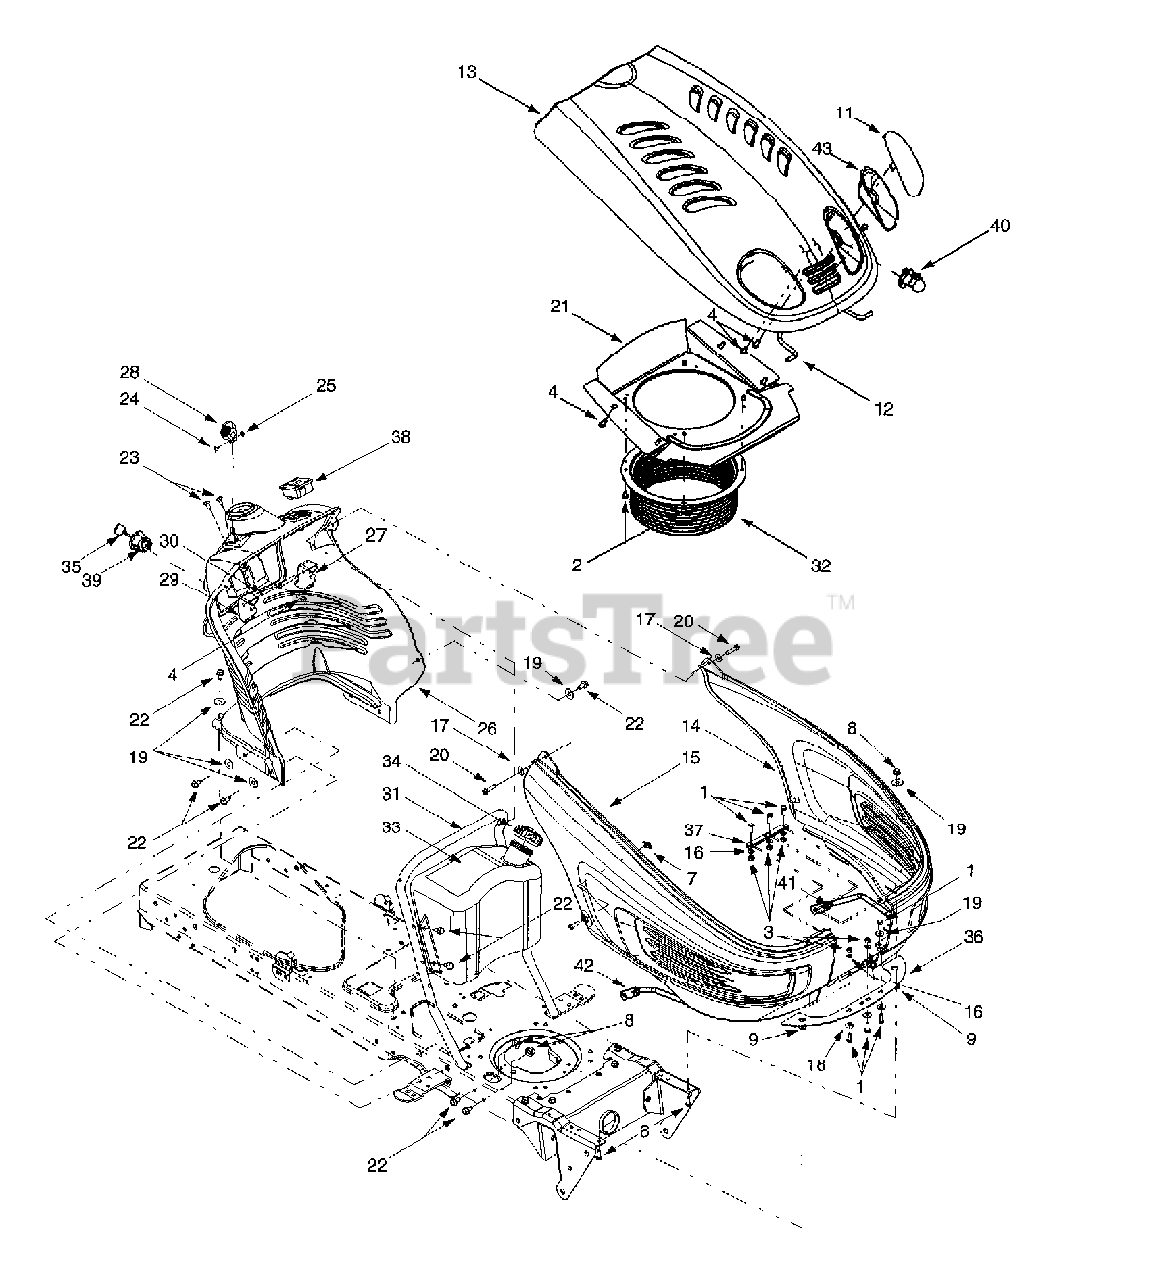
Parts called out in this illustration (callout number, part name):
1	Hex Cap Screw, 1/4-20 x .75
2	Self-tapping Screw, 1/4-20 x.5
3	Hex Nut, 1/4-20
4	Self-tapping Screw, 1/4-15 x .75
6	Hex Cap Screw, 5/16-18 x 1.25
7	U-type Speed Nut, 1/4-20
8	Flange Lock Nut, 5/16-18
9	Speed Nut
11	RH Head Light Lens
12	Hood Support Rod
13	Hood
14	LH Side Panel
15	RH Side Panel
16	Lock Washer, 1/4
17	Flat Washer, .283 x .75 x .030
18	Flat Washer, .28 x .74 x .063
19	Flat Washer, .349 x 1.0 x .063
20	Self-tapping Screw, 1/4-20 x 1.25
22	Self-tapping Screw, 5/16-18 x .625
23	Torx Self-tapping Screw, 1/4-14 x .625
24	Torx Screw, #8-32 x .375
25	Hex Nut, 8-32
26	Dash Panel, 4-style
27	Parking Brake Button
28	Throttle Control Lever
29	Cruise Control Button
30	Brake/Cruise Pivot Rod
33	Fuel Tank, 3-gallon
34	Fuel Cap
35	Ignition Key w/ plastic cover
36	Heat Shield
39	Ignition Switch
40	Headlight Assembly
